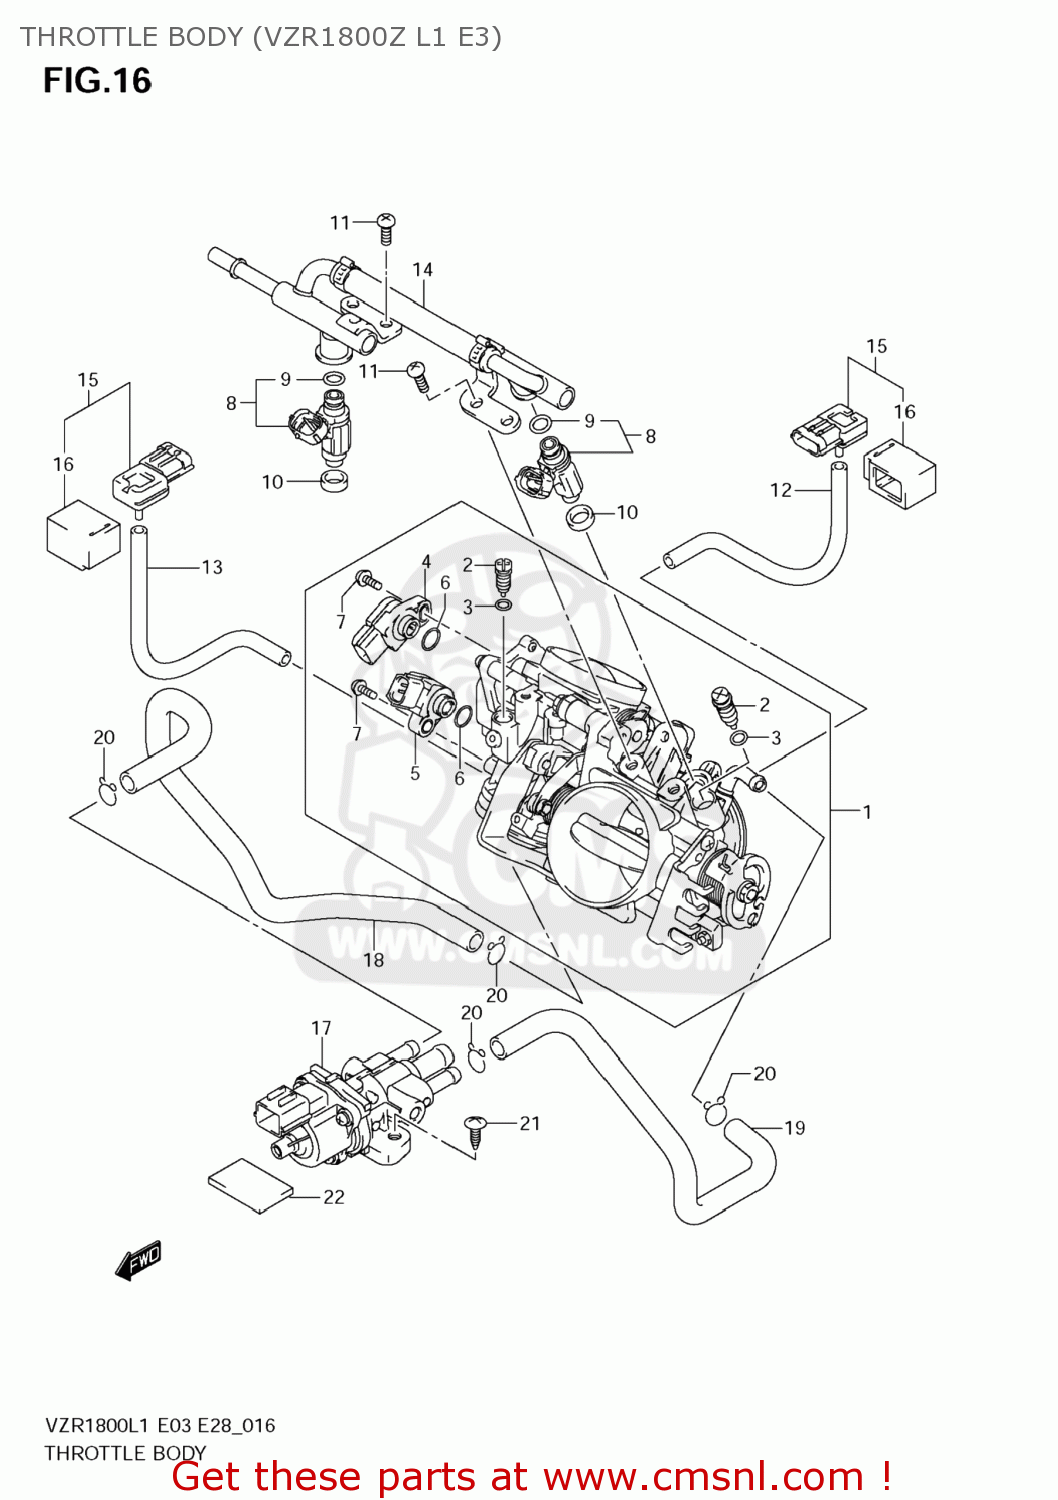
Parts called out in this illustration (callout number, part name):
1	BODY ASSY,THROTTLE
2	ADJUSTER
3	O RING
4	SENSOR ASSY
5	SENSOR ASSY
6	O RING
7	SCREW
8	INJECTOR ASSY
9	O-RING
10	SEAL
11	SCREW
12	HOSE
13	HOSE
14	PIPE ASSY,DELIVERY
15	SENSOR,AIR PRESSURE
16	COVER
17	VALVE,ISC
18	HOSE,ISC VALVE,R
19	HOSE,ISC VALVE,L
20	CLIP
21	SCREW
22	CUSHION,FUEL TANK NO.2
